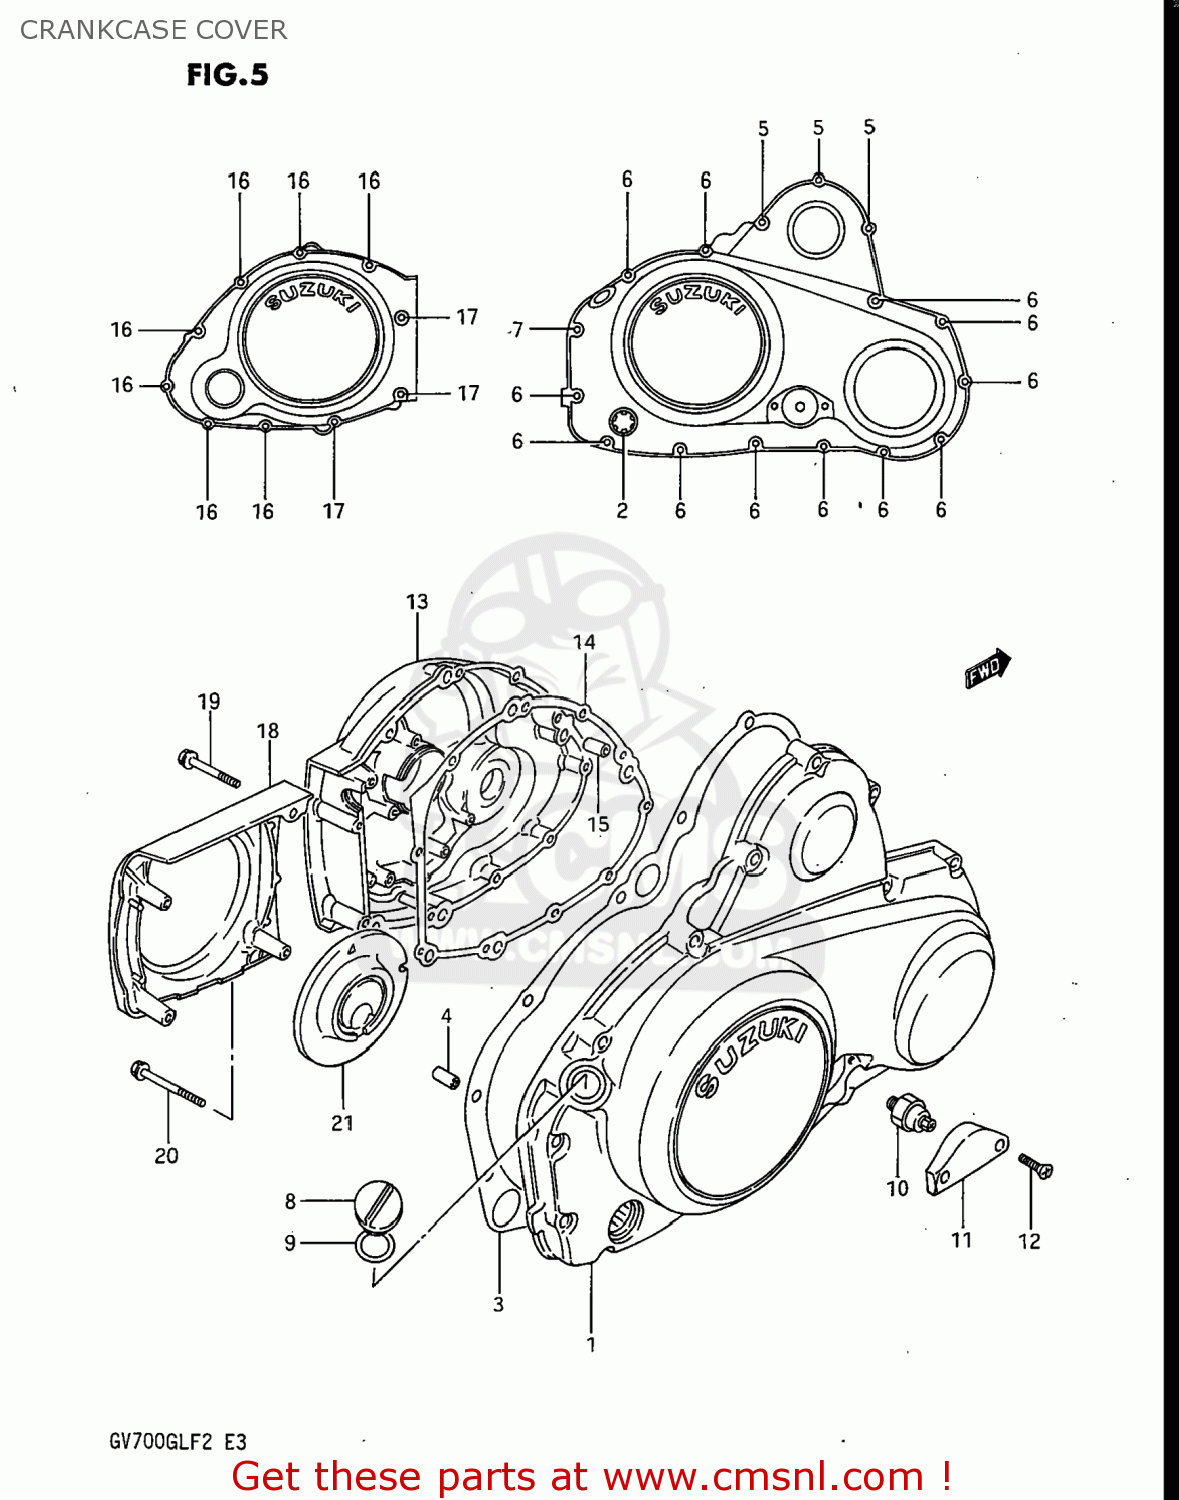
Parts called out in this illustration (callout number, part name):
1	COVER,CLUTCH
2	LENS,OIL LEVEL CHECK
3	GASKET,CLUTCH COVER (MCA)
4	PIN
5	BOLT 6X30
6	BOLT
7	BOLT
8	PLUG(20X10)
9	O RING(D:3.1,ID:16.8)
10	SWITCH ASSEMBLY
11	CAP,OIL PRESSURE SWITCH
12	SCREW
13	COVER,GENERATOR
14	GASKET,MAGNETO COVER (MCA)
15	PIN (11X20)(SUS)
16	BOLT
17	BOLT
18	COVER,SECONDARY DRIVE
19	BOLT
20	BOLT
21	DAMPER
